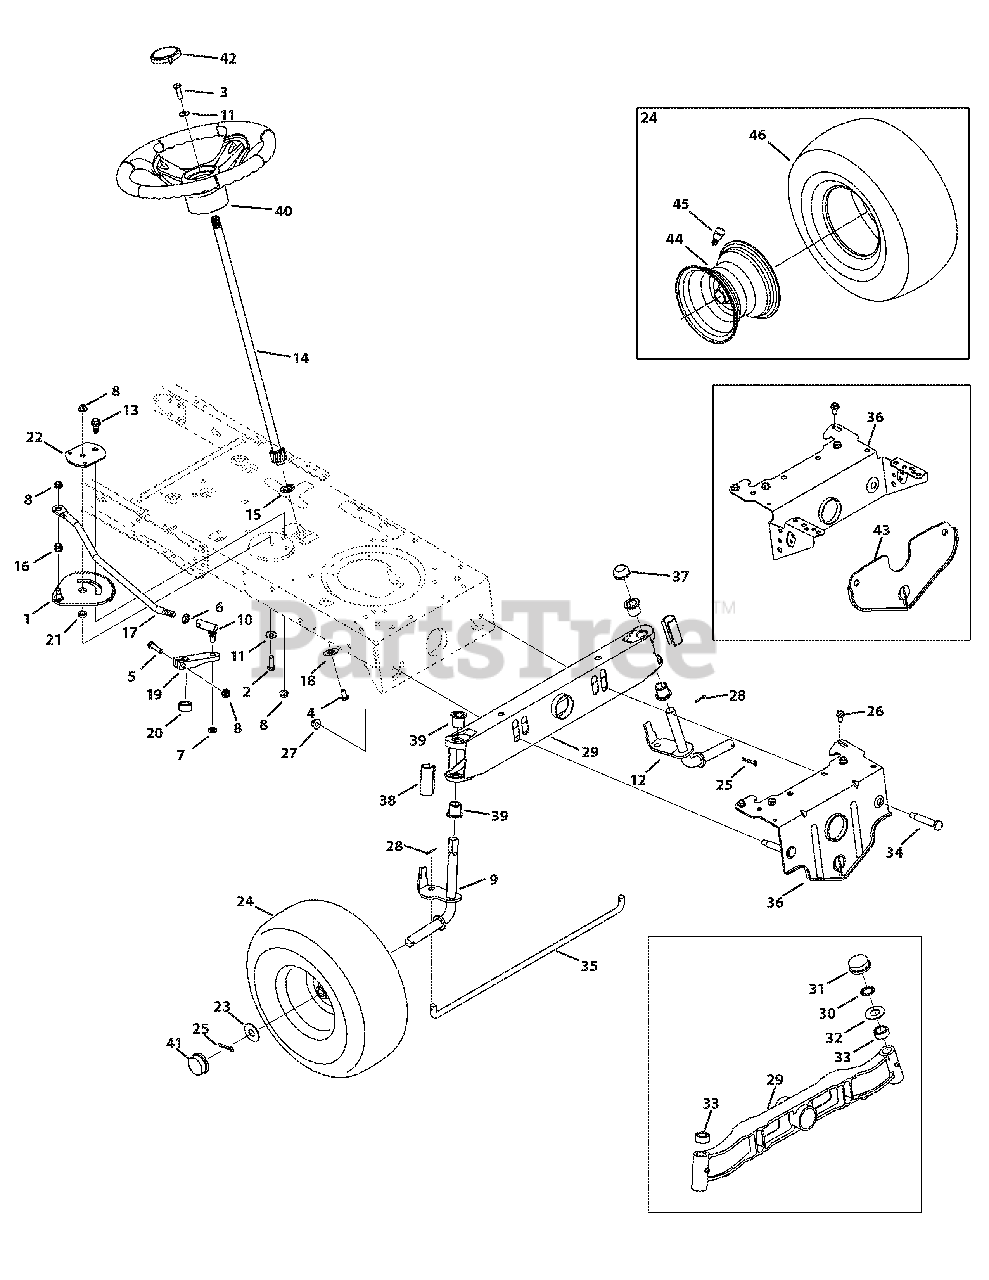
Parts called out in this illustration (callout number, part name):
1	Front Steering Gear Assembly
2	Hex Screw, 5/16-18 x 1.00
3	Hex Screw, 5/16-18 x 1.00, Lock
4	Machine Screw, 5/16-18 x .750
5	Hex Screw, 5/16-18 x 1.75
6	Jam Nut, 7/16-20
7	Jamlock Nut, 3/8-24
8	Flangelock Nut, 5/16-18
9	Front RH Axle w/46" deck
9	Front RH Axle
10	Ball Joint, 7/16-20
11	Bell Washer, .340 x .872 x .060
12	Front LH Axle w/46" deck
13	Shoulder Bolt, 5/16-18 x .435 x .350
14	Steering Shaft, 5/8 x 22.08
15	Flange Bearing, 5/8
16	Plastic Bushing, .380 ID
17	Steering Link
18	Cap, 1.25 x .16
19	Steering Block
20	Spacer, .71 x .125 x .56
21	Spacer, .322 x .625 .21
22	Gear Segment Stabilizer Plater
23	Flat Washer, .781 x 1.590
24	Wheel Assembly
25	Cotter Pin, 5/32 x 1.25
26	Screw, 5/16-18 x .750
27	Flangelock Nut, 3/8-16
28	Cotter Pin, .125 x .75
29	Pivot Axle
30	Push Nut, 3/4
32	Flat Washer, .78 x 1.59 x .060
33	Spacer, .71 x .125 x .56
34	Shoulder Bolt, 3/8-16 x .500 x 2.38
36	Pivot Bar Bracket
37	Push Cap, 3/4
38	Standard Axle Cap
39	Flange Bearing, .760 x .941 x 1.0
40	Steering Wheel
42	Cap, Troy-Bilt
43	Front Deck Hanger Bracket
44	Deck Rim Asm, 6.0x4.5
45	Valve, tubeless Air
46	Tire, 15 X 6 X 6 Sq Shoulder
46	Tire, 15 X 6 X 6 Rd Shoulder
